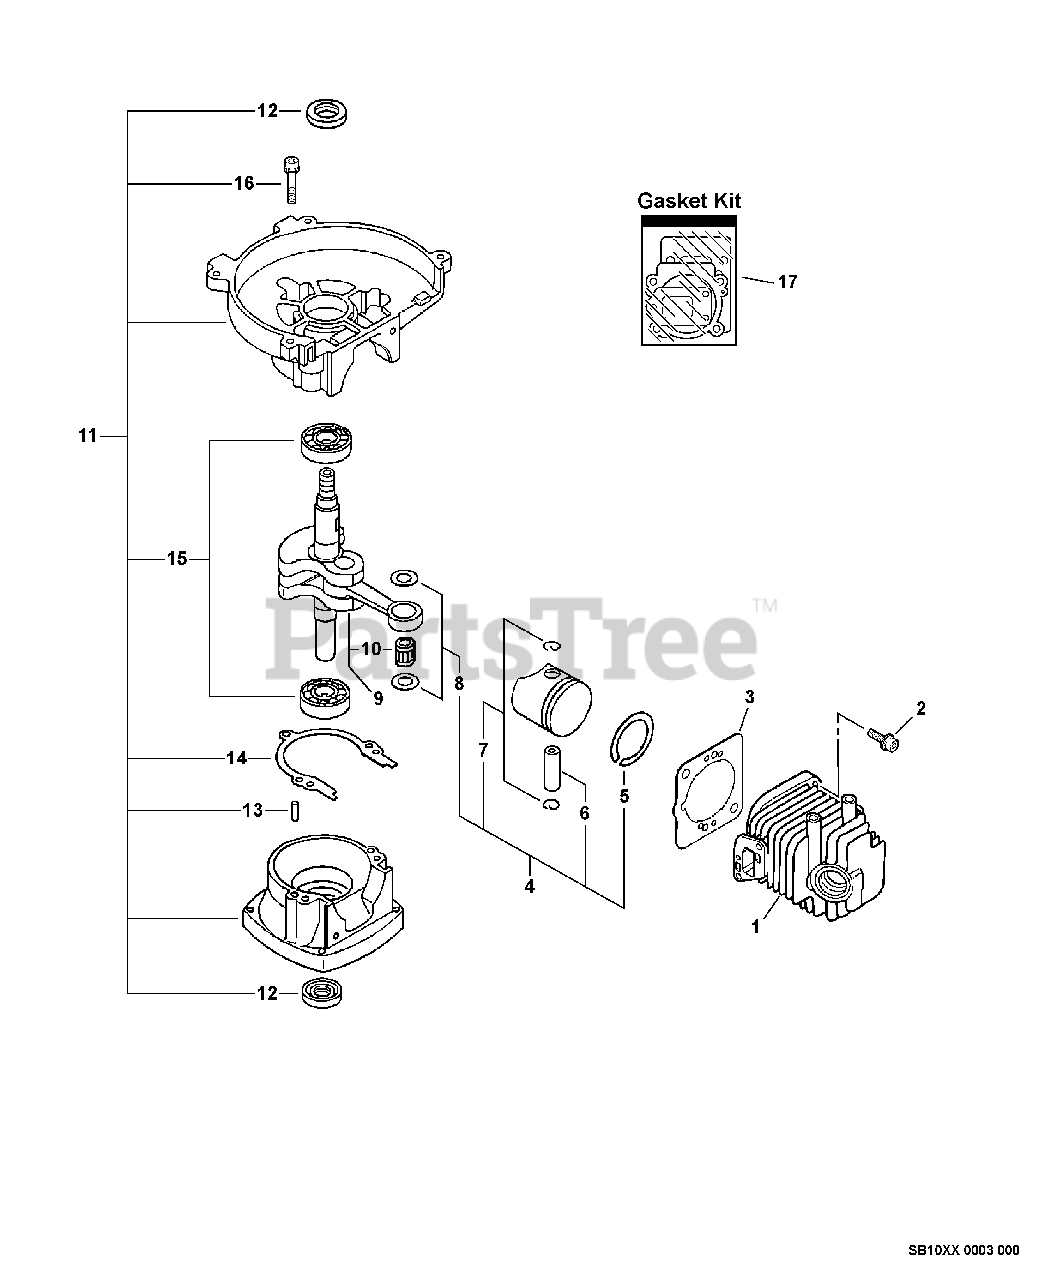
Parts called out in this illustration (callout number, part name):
1	CYLINDER
2	BOLT 5×22
3	GASKET, CYLINDER
4	PISTON KIT
5	RING, PISTON
6	PIN, PISTON 8
7	RING, SNAP
8	WASHER, THRUST
9	CRANKSHAFT ASSY
10	BEARING, NEEDLE 8
11	CRANKCASE KIT
12	SEAL, OIL 12
13	PIN, LOCATING 4
14	GASKET, CRANKCASE
15	BEARING, BALL - 6201 C3
16	BOLT 5×28
17	GASKET KIT
